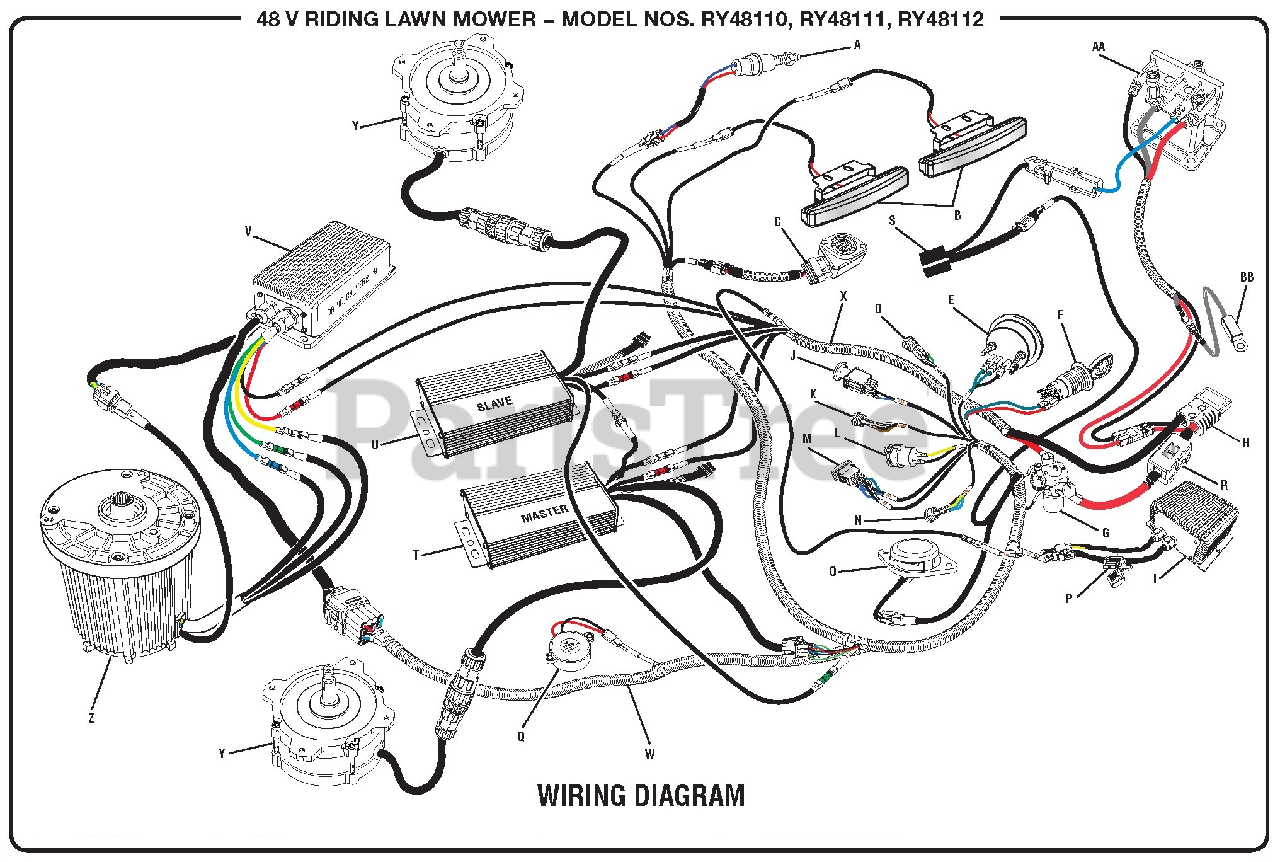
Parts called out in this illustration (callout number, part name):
A	Brake Switch
B	Headlights
C	Accelerator
D	Cruise
E	Battery Gauge
F	Switch w/Key
G	Relay
H	Battery Connector
I	12 Volt Power Converter
J	Blade PTO
K	Headlight Switch
L	USB
M	Forward/Netural/Reverse
N	Reverse Mow Operation
O	Seat Switch
P	25 Amp Fuse
Q	Beeper
R	125 Amp Fuse
S	Charger Lockout Circuit
T	Master Deck Motor Controller
U	Slave Deck Motor Controller
V	Drive Motor Controller
W	Main Wiring Harness
X	Sub Wiring Harness
Y	Deck Motor
Z	Drive Motor
AA	Charger Port
BB	Temperature Sensor
